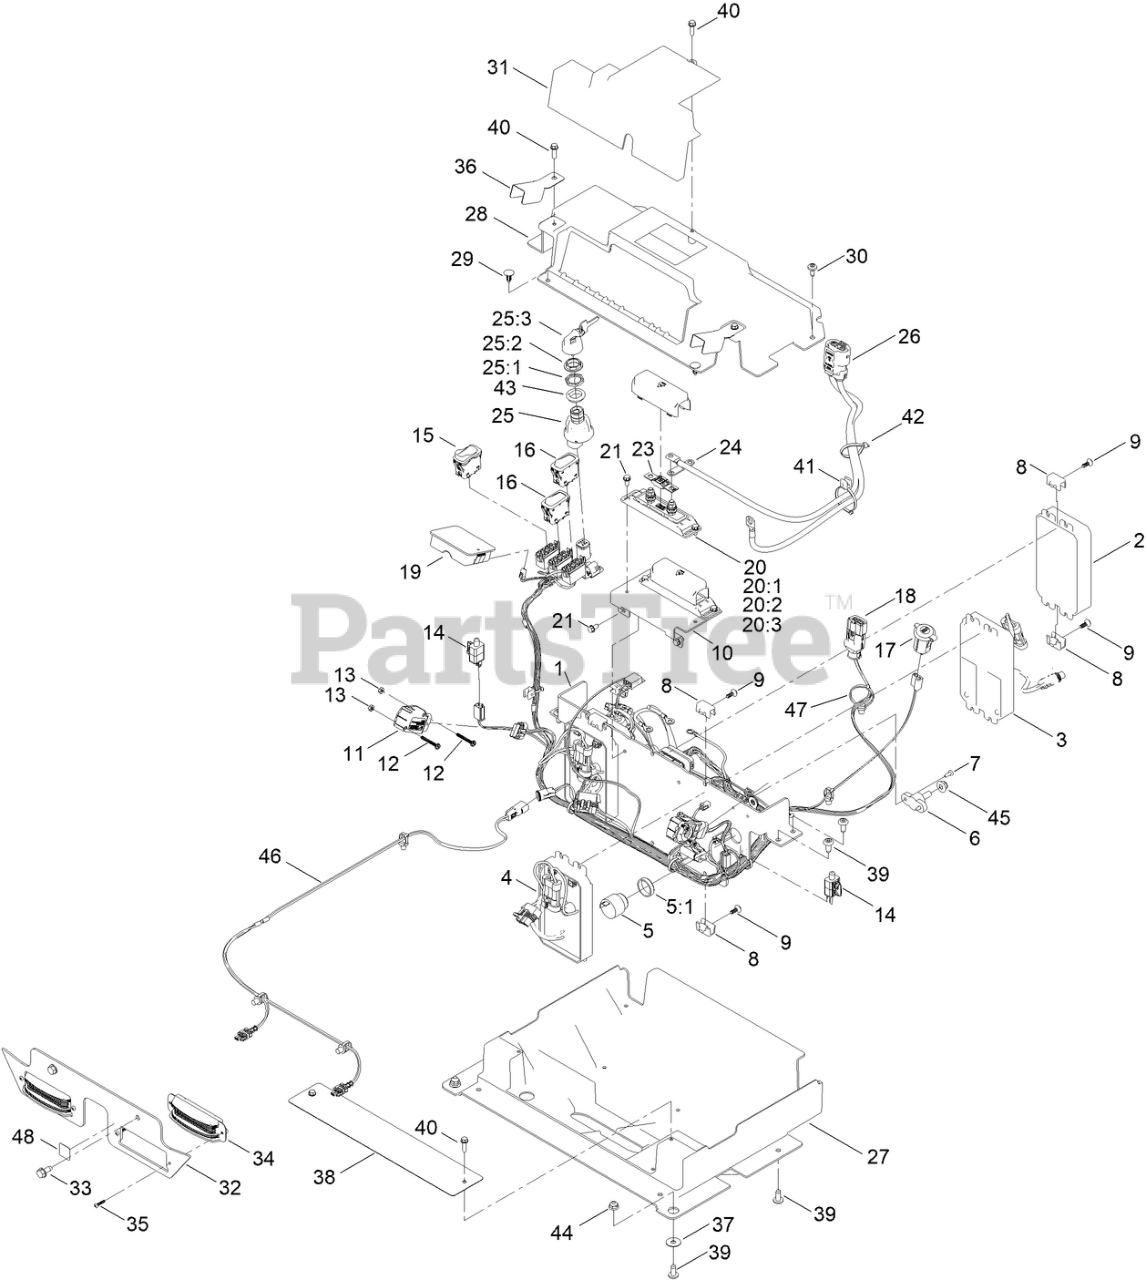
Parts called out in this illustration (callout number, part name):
1	MOUNT-CONTROLLERS
2	CONTROLLER-MASTER
3	CONTROLLER-TRACTION
4	CONTROLLER-DECK
5	AUDIO ALARM ASM
5:1	NUT-PLASTIC, KNURLED
6	BLOCK-JUNCTION
7	SCREW-FORMING, THREAD
8	CLIP-CONTROLLER
9	SCREW-DELTA POINT
10	MOUNT-HOLDER, FUSE
11	SENSOR
12	SCREW-HWH
13	NUT-HEX NI
14	SWITCH
15	SWITCH-ROCKER, ON-NONE-ON
16	SWITCH-ROCKER ON- NONE- ON
17	PORT-POWER, USB
18	HARNESS-WIRE, 2 BLADE
19	DISPLAY
20	HOLDER-FUSE
20:1	WASHER-LOCK
20:2	WASHER-FLAT
20:3	NUT-HEX
21	SCREW-HWH
23	FUSE-100 AMP
24	BUSBAR-2, SWITCH
25	SWITCH-IGNITION, SUNS
25:1	NUT-HEX
25:2	NUT-FACE, M22 (PLASTIC)
25:3	SET-KEY, IGNITION
26	HARNESS-WIRE, POWER CABLE
27	COVER-BOTTOM
28	COVER-CONTROLLER
29	PLUG-PLASTIC
30	SCREW-SHOULDER
31	COVER-OUTER
32	MOUNT-HEAD LIGHTS
33	SCREW-HWHTF
34	ASM-LIGHT,LED
35	SCREW-PPH
36	COVER-SENSOR
37	WASHER
38	COVER-WIRE
40	SCREW-PLASTITE, HWH
41	CLIP-EDGE
42	TIE-CABLE
43	ADAPTER-SWITCH, KEY
44	NUT-HF
45	NUT-HF, NI
46	HARNESS-WIRE, LED LIGHTS
47	CLIP-TIE
